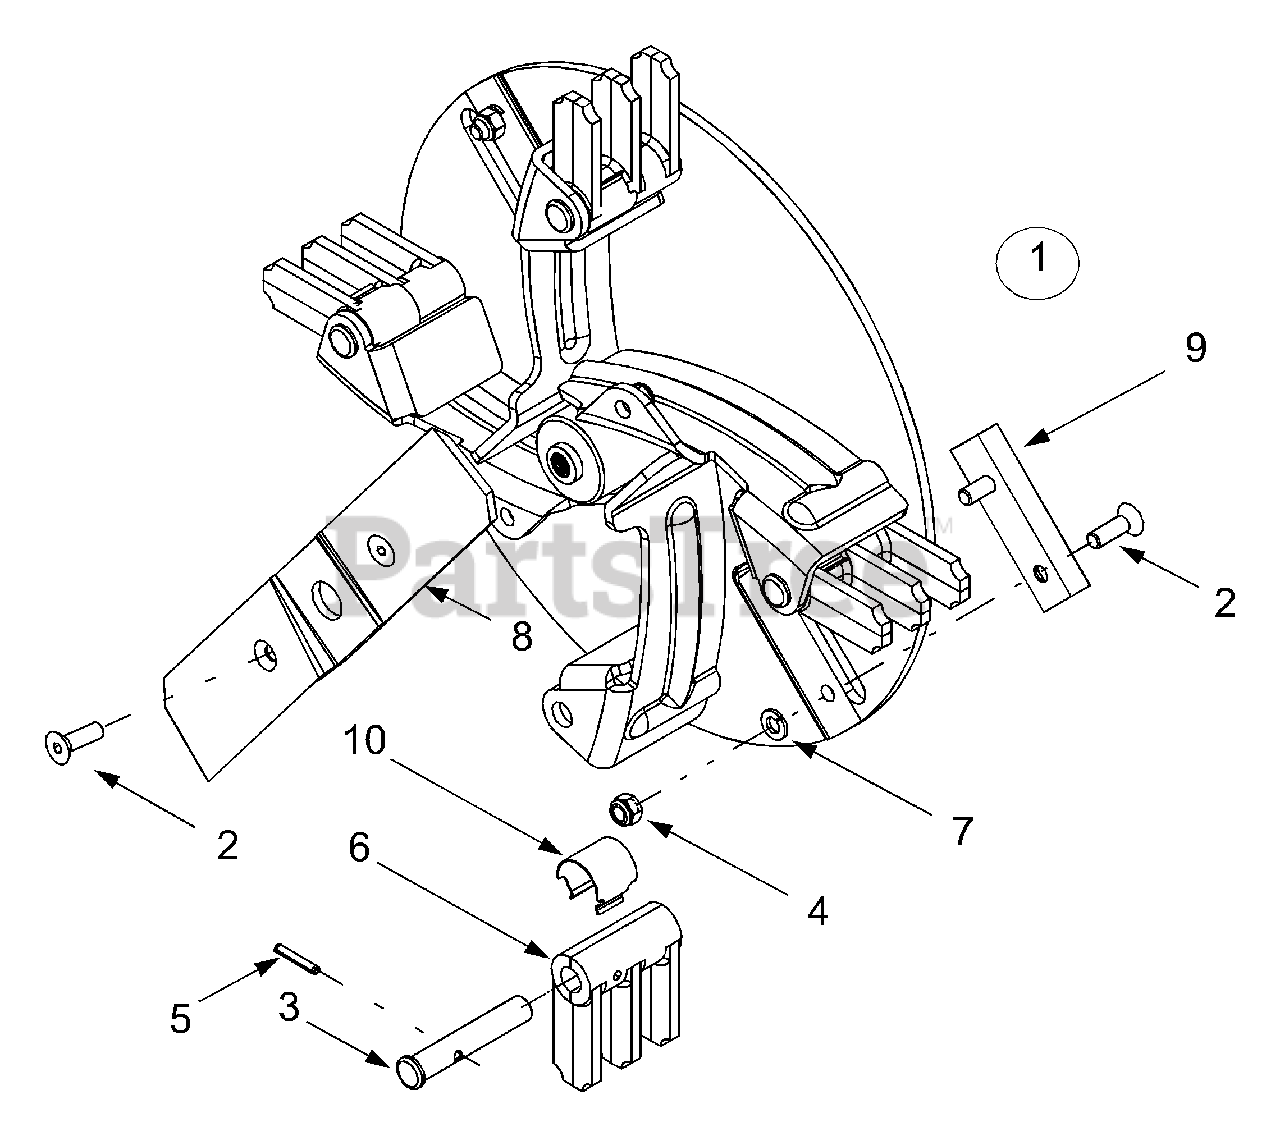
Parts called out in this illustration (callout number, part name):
1	Impeller Assembly Complete
2	Machine Screw, 5/16-24 x 1.0
3	Clevis Pin,.496
4	Hex Lock Nut, 5/16-24
5	Spiral Pin,.156 x 1.0
6	Flail
7	Lock Washer, 5/16
8	Shredder Blade
9	Chipper Blade
10	Retainer Clip
